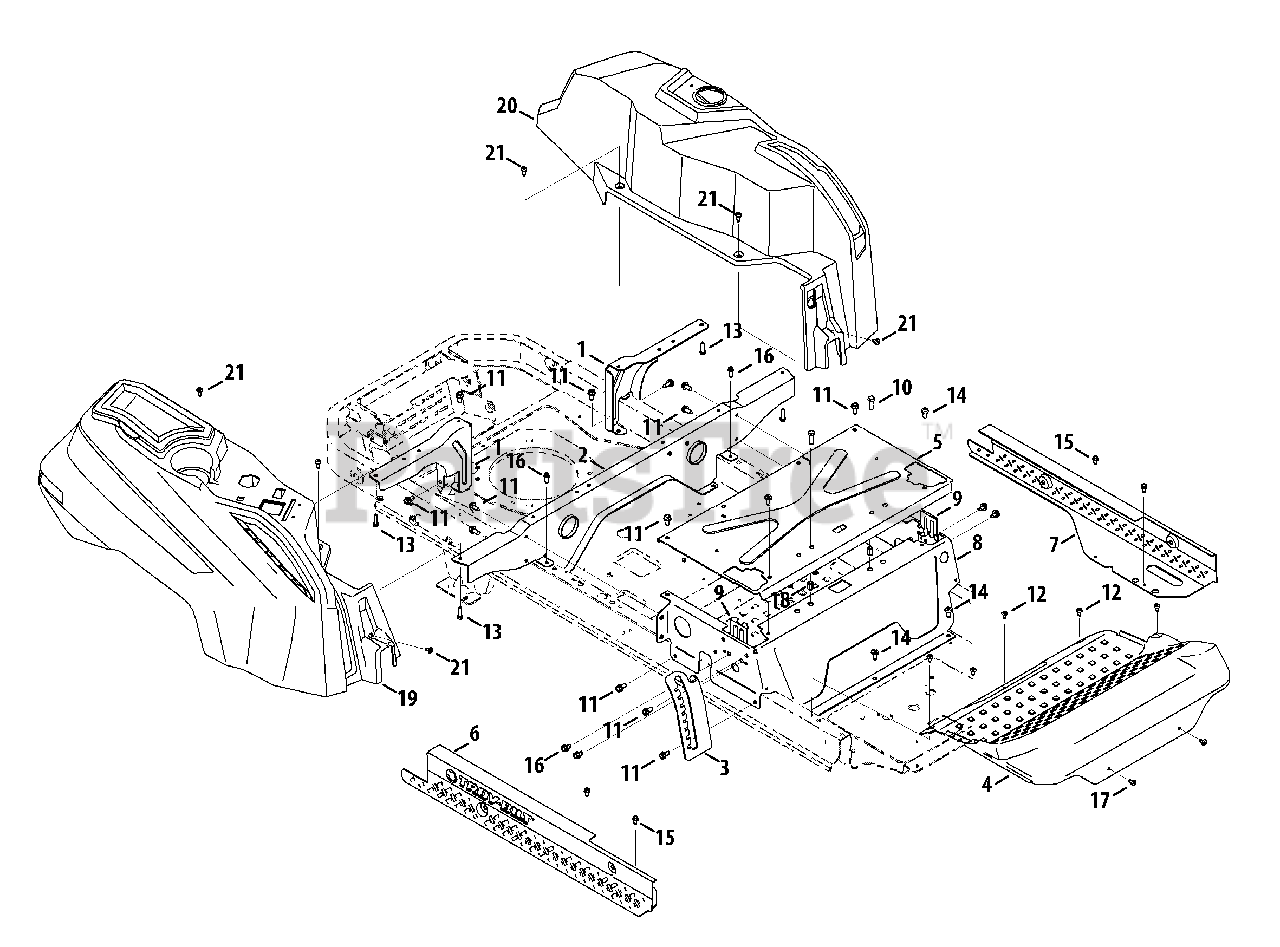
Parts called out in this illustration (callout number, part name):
1	Rear Tank Bracket
2	Rear Seatbox Brace
3	Height Index Bracket
4	Floor Board
5	Seatbox Plate
6	Frame Support, RH
7	Frame Support, LH
9	Lapbar Brace Bracket
10	Hex Cap Screw, 5/16-18 x 1.00
11	Hex Washer Screw, 5/16-18 x .750
12	Screw, 1/4-20 x .500
13	Hex Washer Screw, 5/16-14 x 1.00
14	Self Tapping Screw, 5/16-18 x .750
15	Hex Washer Screw, 1/4-20 x .500
16	Hex Washer Screw, 5/16-18 x .50
17	Self Tapping Screw, 5/16-18 x .750
18	Nut, 5/16-18
19	RH Console
20	LH Console
21	Shoulder Screw, 1/4-20
